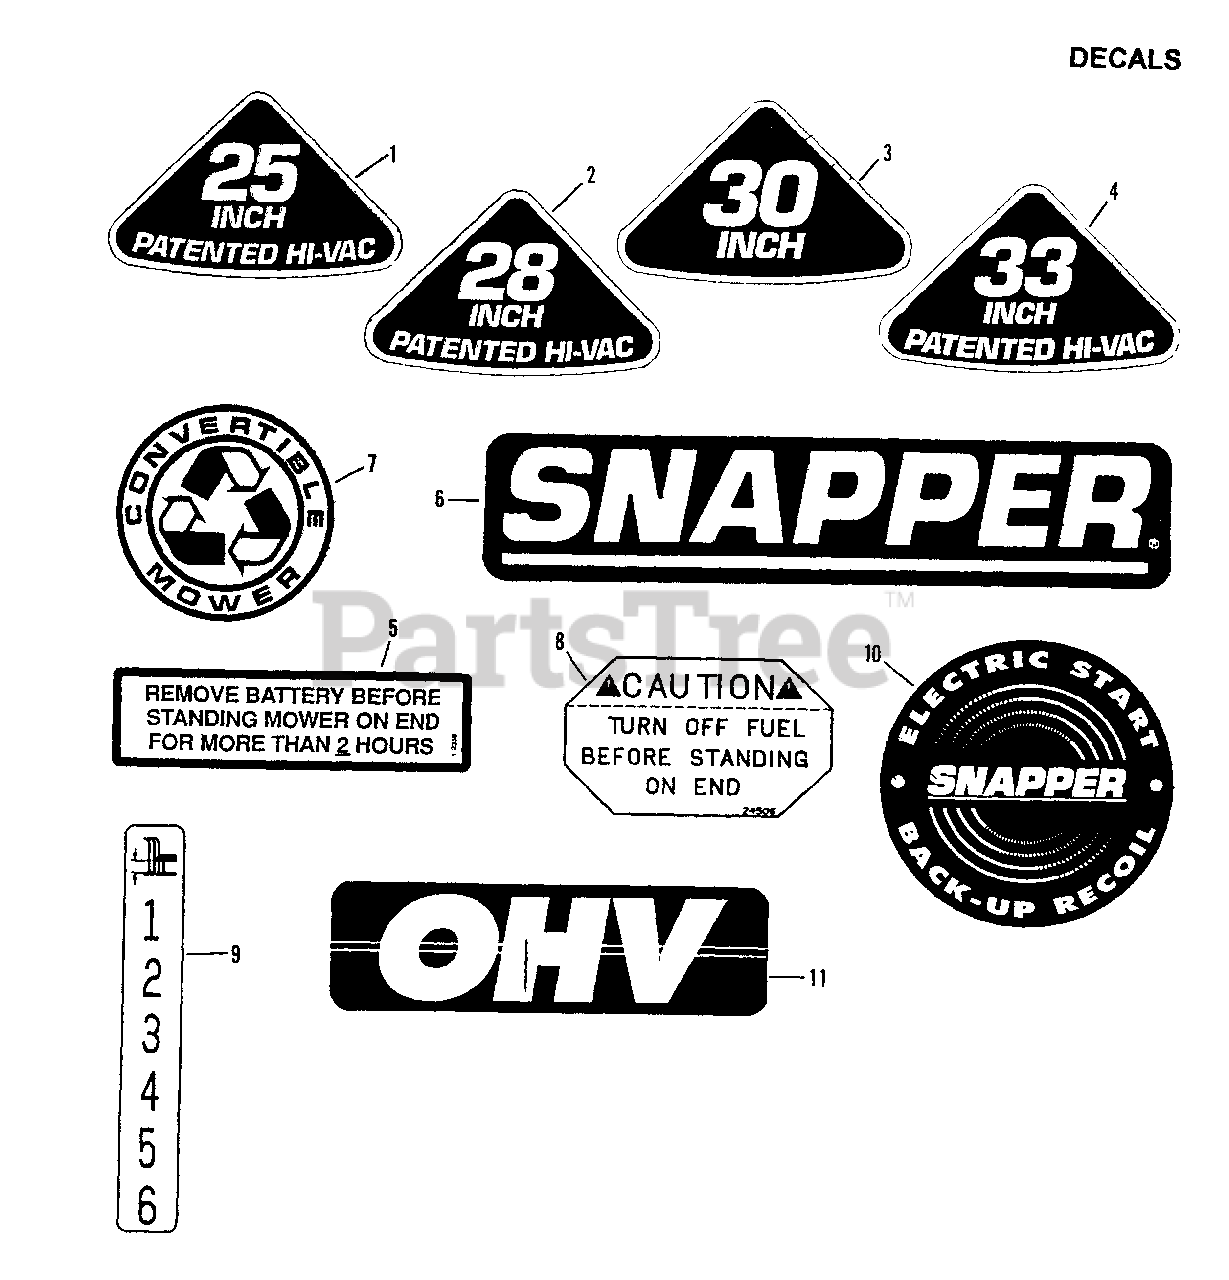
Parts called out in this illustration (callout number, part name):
1	DECAL, 25 Inch
2	DECAL, 28 Inch
3	DECAL, 30 Inch
4	DECAL, 33 Inch
5	DECAL, Battery
6	SNAPPER, (Molded Logo)
7	LOGO, Convertible (Silver)
7	LOGO, Convertible (Teal)
7	LOGO, Convertible (Blue)
8	DECAL, Fuel Shut-Off
9	DECAL, Height of Cut
10	DECAL, Back-Up Recoil
11	DECAL, OHV
